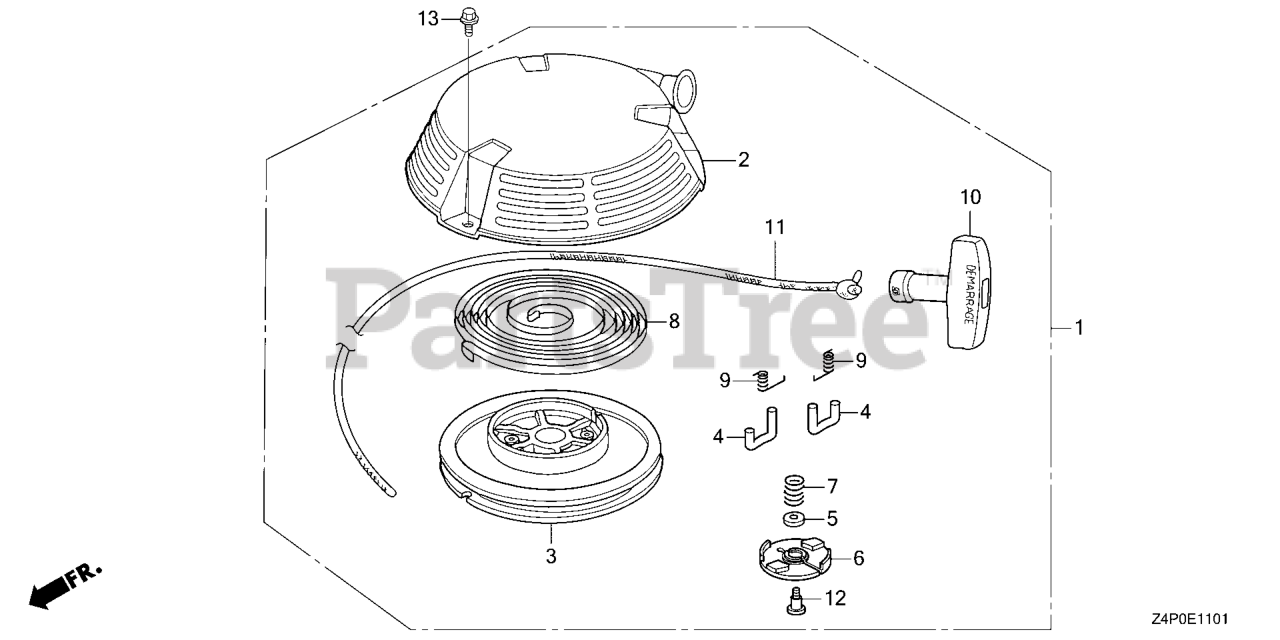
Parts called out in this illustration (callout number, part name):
1	STARTER ASSY., RECOIL *NH1* (BLACK)
1	STARTER ASSY., RECOIL *R280* (POWER RED)
2	CASE, RECOIL STARTER *NH1* (BLACK)
2	CASE, RECOIL STARTER *R280* (POWER RED)
3	REEL, RECOIL STARTER (BLACK)
4	RATCHET, STARTER
5	PLATE, FRICTION
6	GUIDE, RATCHET
7	SPRING, FRICTION
8	SPRING, RECOIL STARTER
9	SPRING, RETURN
10	GRIP, STARTER
11	ROPE, RECOIL STARTER
12	SCREW, SETTING
13	BOLT, FLANGE (6X8)
